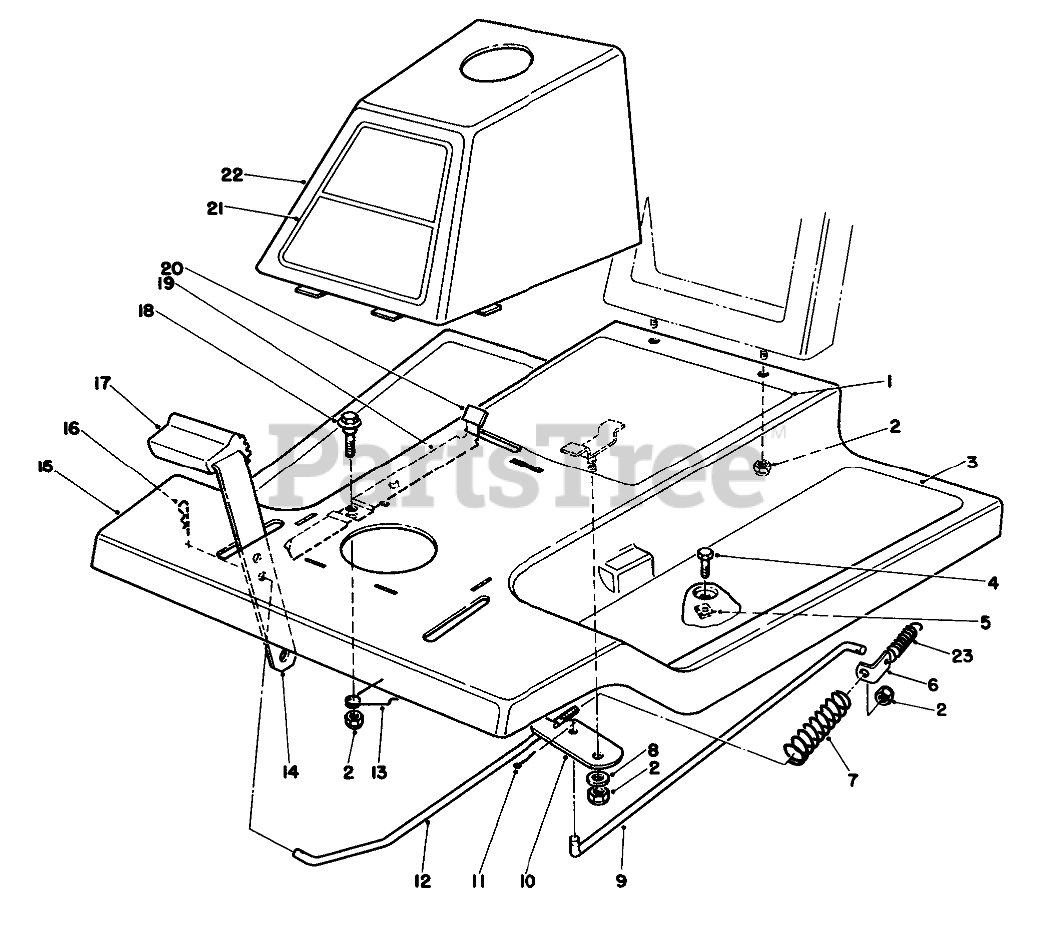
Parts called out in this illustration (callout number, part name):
1	DECAL - INSTRUCTION
2	NUT-LOCK, NI
3	TREAD-FOOT
4	SCREW-HH
5	NUT-TINNERMAN
6	BRACKET-BRAKE RETURN
7	SPRING-TRACTION BRAKE
8	WASHER-PIVOT
9	ROD-TRANS BRAKE
10	Lever-Brake, Bellcrank
11	PIN-COTTER
12	ROD-FRONT BRAKE
13	SPRING-PARKING BRAKE
14	Pedal-Brake & Clutch
15	Body W.A.-Front
16	PIN-COTTER
17	PAD-PEDAL
18	SCREW-SHOULDER
19	Parking Brake
20	TIP-PARKING BRAKE
21	Decal-825
22	Tower (Incl. Ref. #21)
23	SPRING-IDLER
